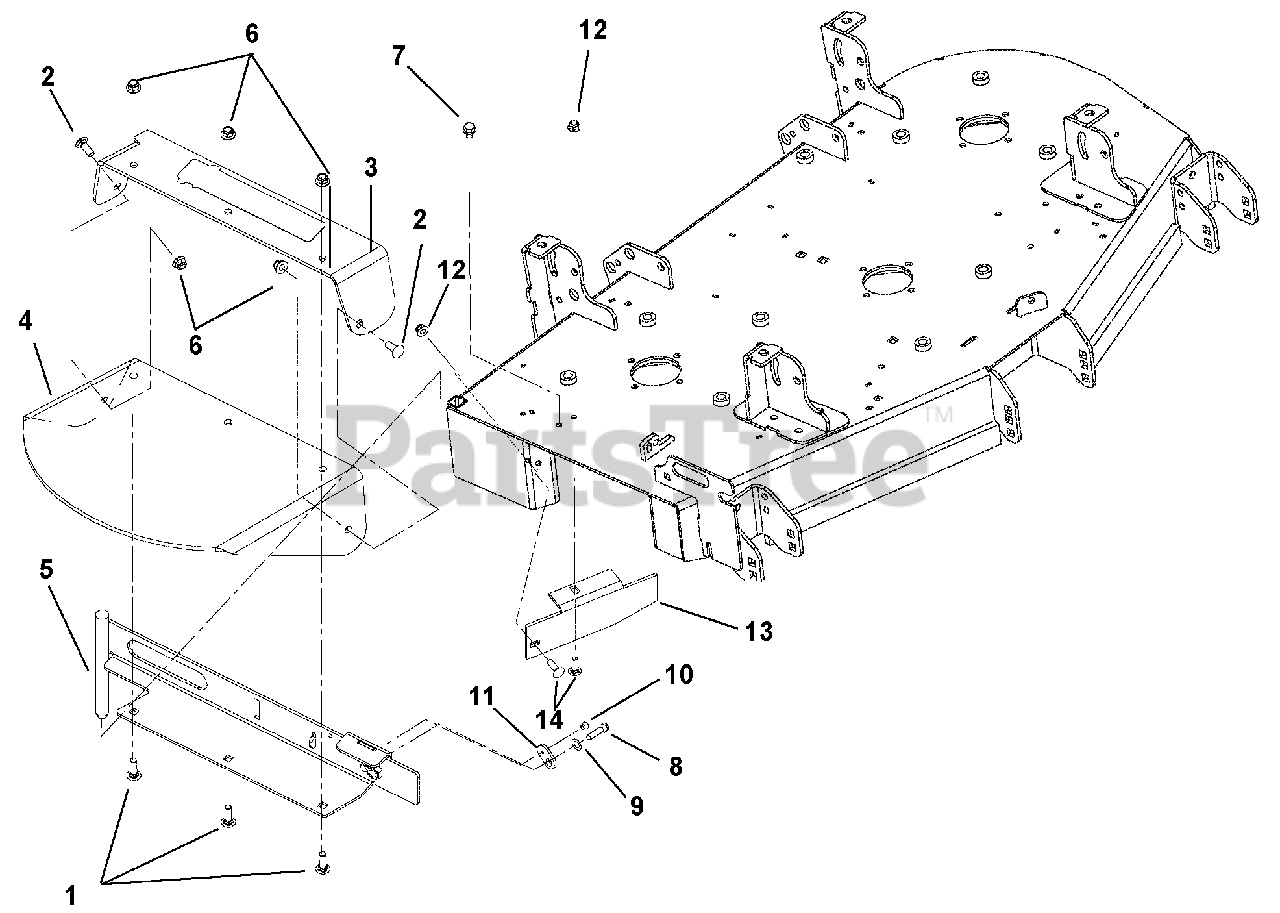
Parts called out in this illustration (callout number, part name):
1	Bolt, Round Head Square Neck .38-16 x 1.25
2	Bolt, Round Head Square Neck .38-16 x 1.00
3	Rubber Discharge Chute Support
4	Chute, Rubber Discharge
5	Weldment, 48" Discharge Chute Mounting, CE
6	Nut, Locking, Nyloc, Flange .38-16
7	Screw, Self Tapping .38-16 x .50
8	Bolt, Hex .38-16 x 1.25
9	Washer, Locking, EXT .391 x .682 x .036
10	Rivet, Pop .187
11	Keeper, Bolt
12	Nut, Locking Nyloc Flange .31 - 18
13	Discharge Baffle
14	Bolt, Round Head Square Neck .31-18 x 1.00
